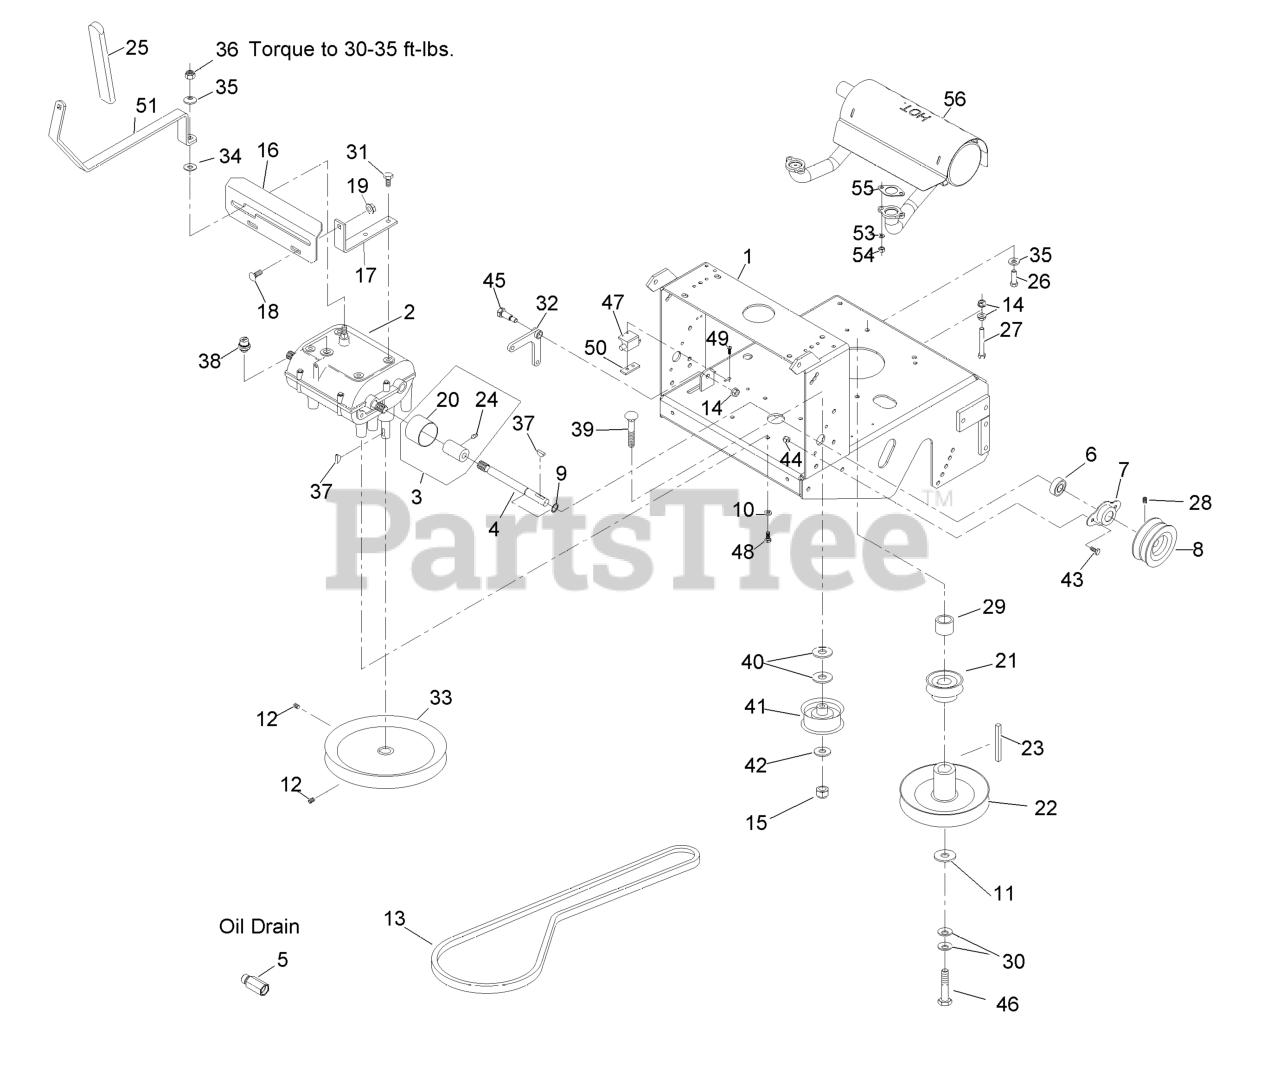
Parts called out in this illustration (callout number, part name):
3	ASM,COUPLER/ZERK
4	SHAFT-TRANSMISSION
5	ADAPTER
6	BEARING-SHAFT
7	FLANGE-OUTPUT
8	SHEAVE-TRANSMISSION
9	RING-RETAINING
10	WASHER-LOCK
12	SCREW-HSH
13	BELT,TRANS DRIVE
14	NUT-HHF, WHIZ
15	NUT-LOCK, NI
16	PLATE,SHIFTER W/DECAL
17	BRACKET-PLATE, SHIFT
18	BOLT-CARR
20	GUARD-COUPLER
21	SHEAVE-TRANSMISSION
24	FITTING-GREASE
25	GRIP,FOAM
26	SCREW-HH
27	SCREW-HH
28	SETSCREW
29	SPACER-CLUTCH
30	WASHER-SPRING
31	SCREW-HWH, THREAD CUT
32	BELLCRANK
33	SHEAVE-TRANSMISSION
35	WASHER-BELLEVILLE
36	NUT-LOCK
37	KEY-WOODRUFF
38	SWITCH-START, NEUTRAL
39	SCREW-HH
40	WASHER-FLAT
42	WASHER-FLAT
43	SCREW-HH
44	NUT-LOCK, NI
45	BOLT-SHOULDER
46	SCREW-HH
47	SWITCH-OPEN, NORMALLY
48	SCREW-HH
49	SCREW-PPH
50	PLATE-TAPPED
51	ASM,SHIFT LEVER
53	WASHER-LOCK
55	GASKET-EXHAUST
56	MUFFLER,HORIZONTAL
